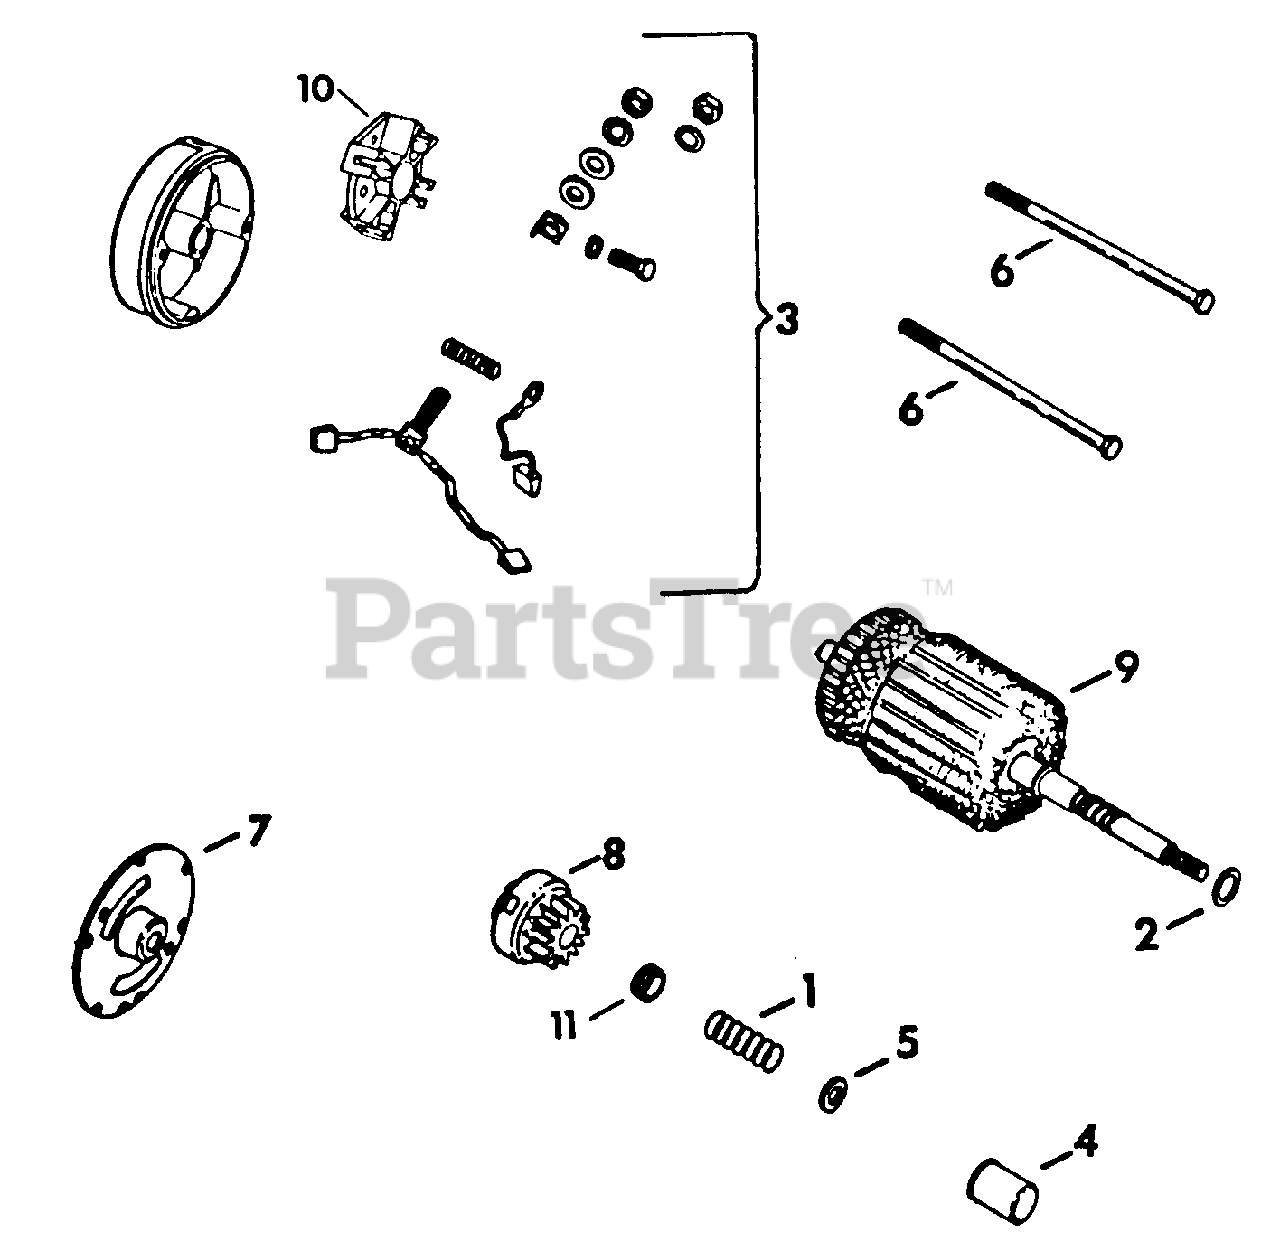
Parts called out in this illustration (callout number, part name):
1	Spring, Anti-Drift
2	Washer, Armature Thrust
3	Cap Assy, Commutator End
4	Cover, Dust
5	Spacer, Stop Gear
7	Cap Assy, Drive End
8	Kit, Drive
9	Armature Assy
10	Holder, Brush
11	Spacer
